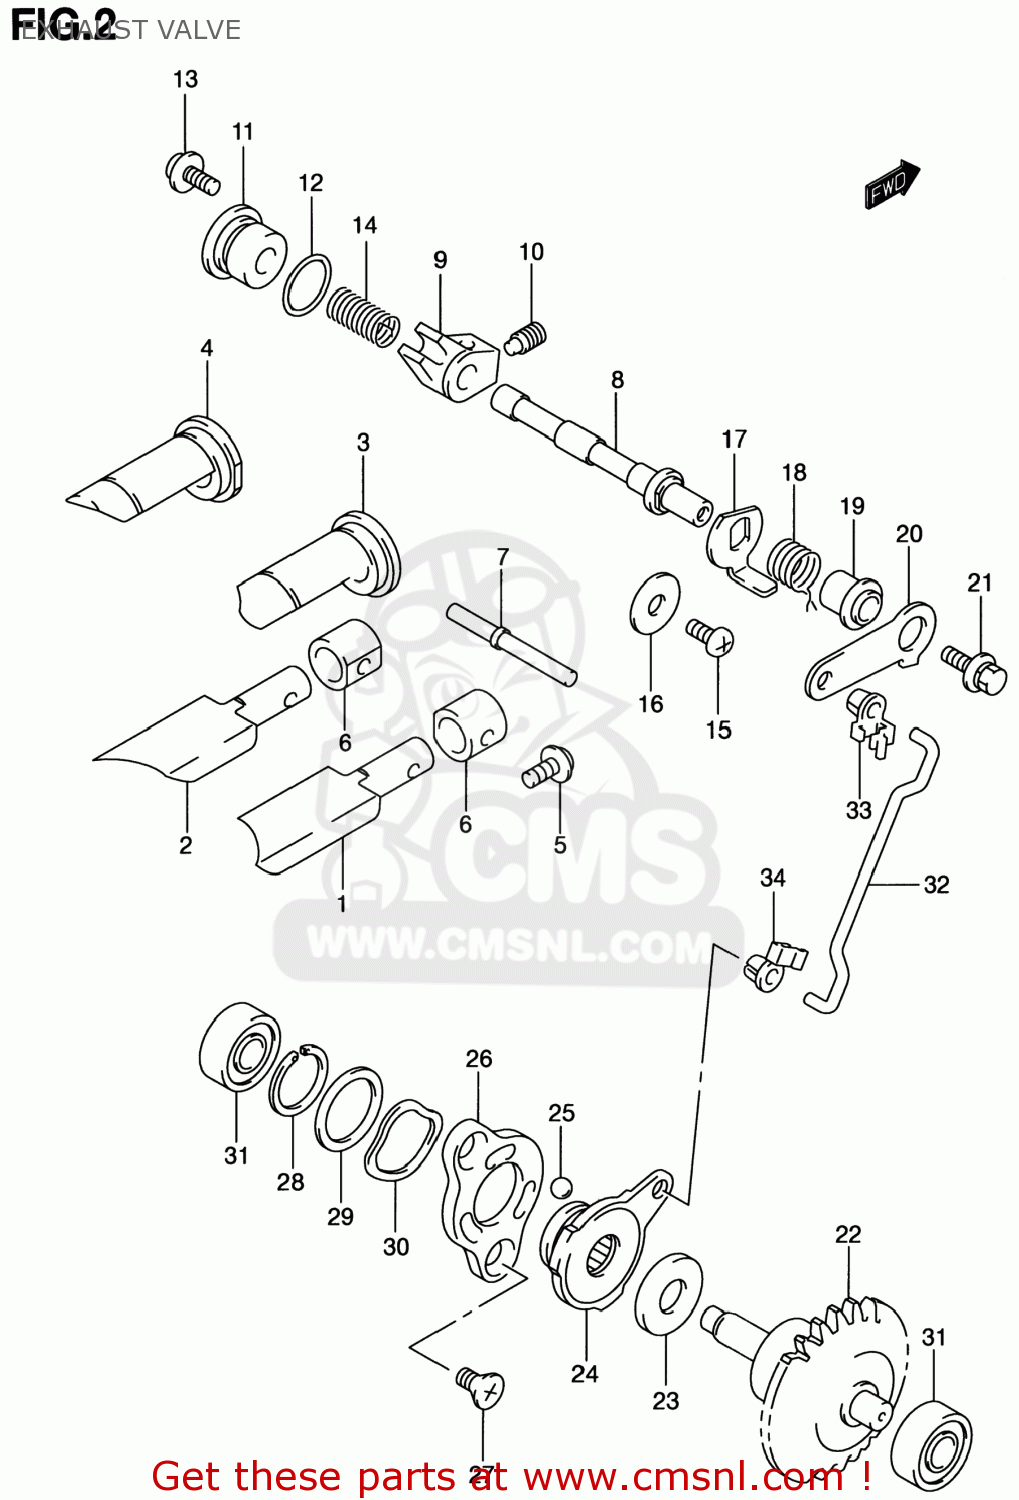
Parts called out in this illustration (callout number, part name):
1	VALVE,EXHAUST,R
2	VALVE,EXHAUST,L
3	GUIDE,EXHAUST VALVE,R
4	GUIDE,EXHAUST VALVE,L
5	SCREW 5X12
6	SPACER,EXHAUST VALVE
7	PIN,EXHAUST VALVE 48.5MM
8	SHAFT,EXHAUST VALVE
9	ARM,EXHAUST VALVE SHAFT
10	SCREW(6X10)
11	CAP,EXHAUST VALVE
12	O RING(D:1.9,ID:14.5)
13	BOLT
14	SPRING
15	SCREW
16	WASHER
17	LEVER,EXHAUST VALVE NO.2
18	SPRING
19	SPACER,EXHAUST VALVE
20	LEVER,EXHAUST VALVE NO.1
21	BOLT(5X12)
22	GOVERNOR ASSY,EXHAUST VALVE
23	BEARING(10X22X2.8)
24	ACTUATOR,EXHAUST VALVE
25	BALL
26	STARTER,EXHAUST VALVE ACTUATOR
27	SCREW(5X10)
28	CIRCLIP
29	SHIM(19.1X25X0.3)
30	WASHER
31	BEARING(8X22X7)
32	ROD,EXHAUST VALVE
33	BUSH,EXHAUST VALVE ROD NO.1
34	BUSH,EXHAUST VALVE ROD NO.2
